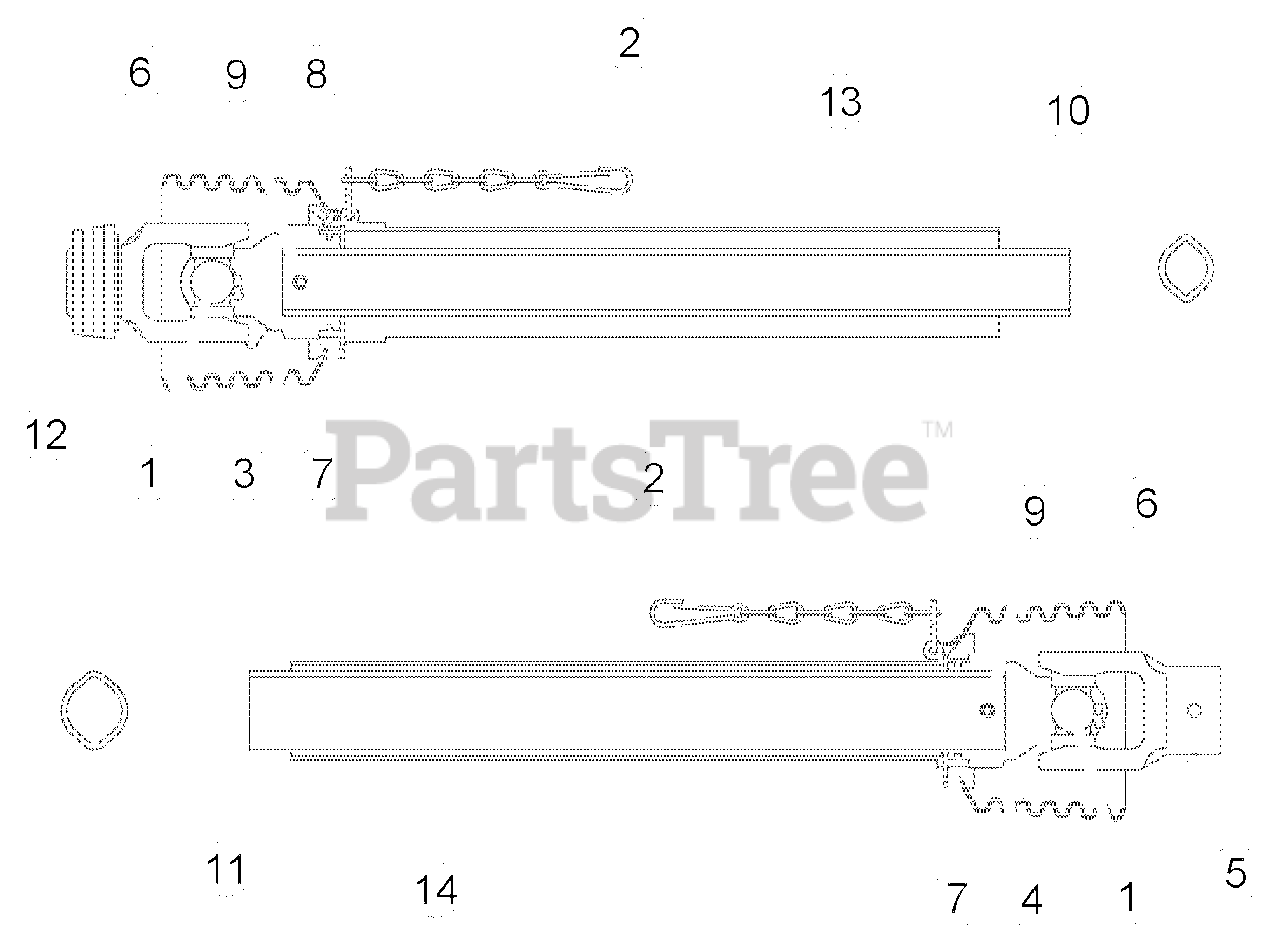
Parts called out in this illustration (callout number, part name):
1	KIT, CROSS & BEARING W-2400
2	CHAIN, SAFETY
3	YOKE, INBOARD 1B
4	YOKE, INBOARD 2A
5	YOKE, 1-1/2" RND
6	CONE, 6 RIB SAFETY
7	RING, SC25 BEARING
8	SCREW, WS365305
9	PIN, M10 X 80 SPRING
10	PROFILE, INNER 1B
11	PROFILE, OUTER 2A
12	YOKE, 1-3/8-6 SPLINGE ASGE
13	GUARD, TUBE OUTER
14	GUARD, TUBE INNER
